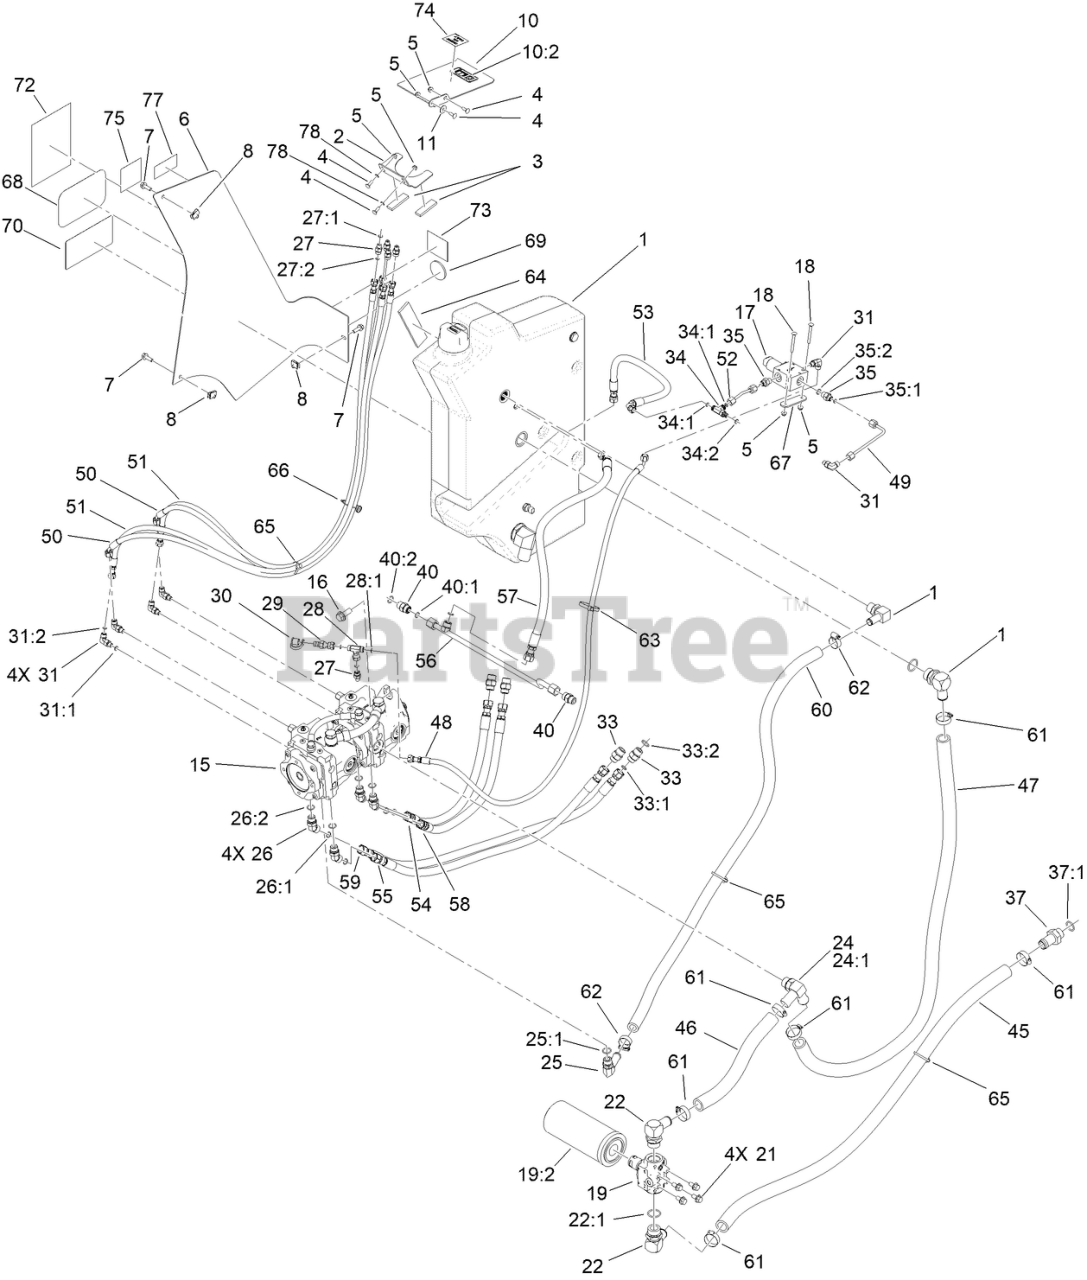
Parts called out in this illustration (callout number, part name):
1	TANK ASM-HYD
2	BRACKET-TANK, HOLD DOWN
3	PAD-FOAM
4	BOLT-CARR
5	NUT-HF
6	TANK COVER ASM-HYD
7	SCREW-HHF
8	NUT-CLIP, U
10	TANK BRACKET ASM-HYD
10:2	DECAL-HYD FLUID
11	WASHER-BELLEVILLE
15	PUMP-TANDEM
16	SCREW-HHF
17	VALVE-PROPORTIONAL PRESSURE REDUCING
18	SCREW-CARR
19	FILTER HEAD ASM
19:2	ELEMENT-FILTER
21	SCREW-HHF
22	STEM-BARB-90
22:1	O-RING
24	CONNECTOR
24:1	O-RING
25	FITTING-90
25:1	O-RING
26	FITTING-HYD, 45 DEG
26:1	O-RING
26:2	O-RING
27	FITTING-STRAIGHT
27:1	O-RING
27:2	O-RING
28	FITTING-TEE
28:1	O-RING
29	NIPPLE-TEST
30	CAP-DUST, RUBBER
31	FITTING-ELBOW, 90 DEG
31:1	O-RING
31:2	O-RING
33	FITTING-STRAIGHT
33:1	O-RING
33:2	O-RING
34	FITTING-TEE
34:1	O-RING
34:2	O-RING
35	FITTING-STRAIGHT
35:1	O-RING
35:2	O-RING
37	FITTING
37:1	O-RING
40	FITTING-STRAIGHT
40:1	O-RING
40:2	O-RING
45	HYD HOSE
46	HYD HOSE
47	HYD HOSE
48	HYD HOSE ASM
49	HYD TUBE ASM
50	HYD HOSE ASM
51	HYD HOSE ASM
52	HYD TUBE ASM
53	HYD HOSE ASM
54	HYD HOSE ASM
55	HYD HOSE ASM
56	HYD TUBE ASM
57	HYD HOSE ASM
58	HYD HOSE ASM
59	HYD HOSE ASM
60	HYD HOSE
61	CLAMP-HOSE
62	CLAMP-HOSE
63	TIE-CABLE
64	PAD-RUBBER
65	CLIP-TIE
66	MOUNT-TIE WRAP, MAGNETIC
67	BRACKET-CLAMP, VALVE
68	DECAL-TORO LOGO
69	REFLECTOR-RED
70	DECAL-TX1000 TURBO
72	DECAL-RHVSG6X8
73	DECAL-RHSQG3X3
74	DECAL-CPER0003
75	DECAL-CPER0811
77	DECAL - CPER0009-03
78	NUT-RETAINING
